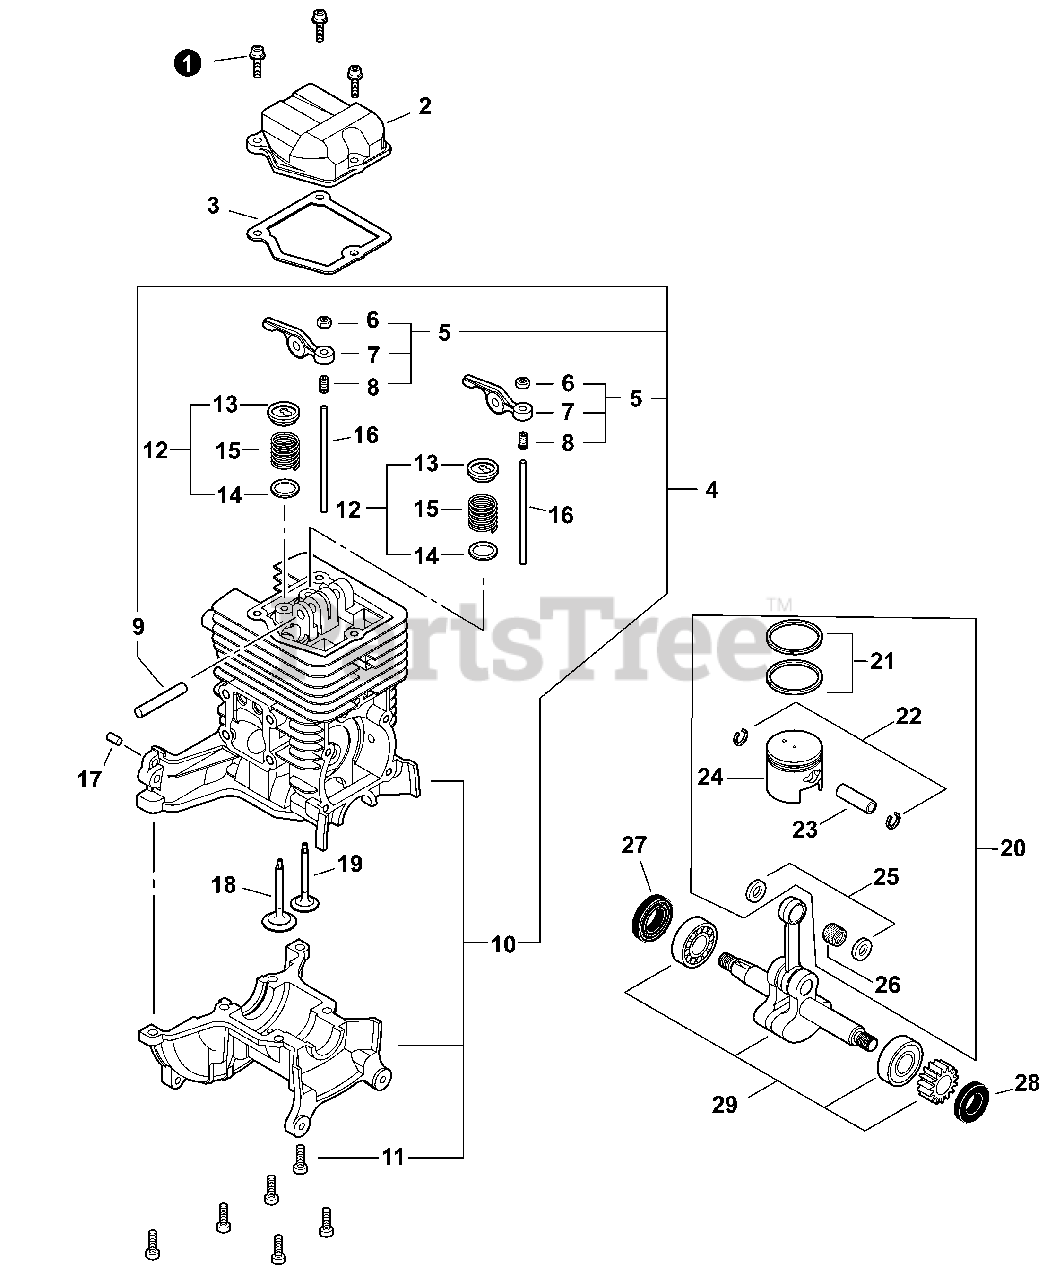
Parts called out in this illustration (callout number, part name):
1	BOLT M4x14
2	COVER, ROCKER ARM
3	GASKET, ROCKER ARM
4	CYLINDER & CRANKCASE ASSY
5	ARM ASSY, ROCKER
6	NUT, ADJUSTER LOCK 5
7	ARM, ROCKER
8	SCREW, ADJUSTER
9	SHAFT, ROCKER ARM ?5x31.8 MM
10	CYLINDER & CRANKCASE ASSY
11	BOLT 5x16
12	RETAINER SET, VALVE
13	RETAINER, VALVE
14	WASHER, VALVE 9
15	SPRING, VALVE
16	PUSHROD
17	PIN, LOCATING 4x8
18	VALVE, INTAKE
19	VALVE, EXHAUST
20	PISTON KIT
21	RING, PISTON
22	RING, SNAP
23	PIN, PISTON
25	WASHER, THRUST 9
26	BEARING, NEEDLE 9
27	SEAL, OIL 12
28	SEAL, OIL 12
29	CRANKSHAFT ASSY
